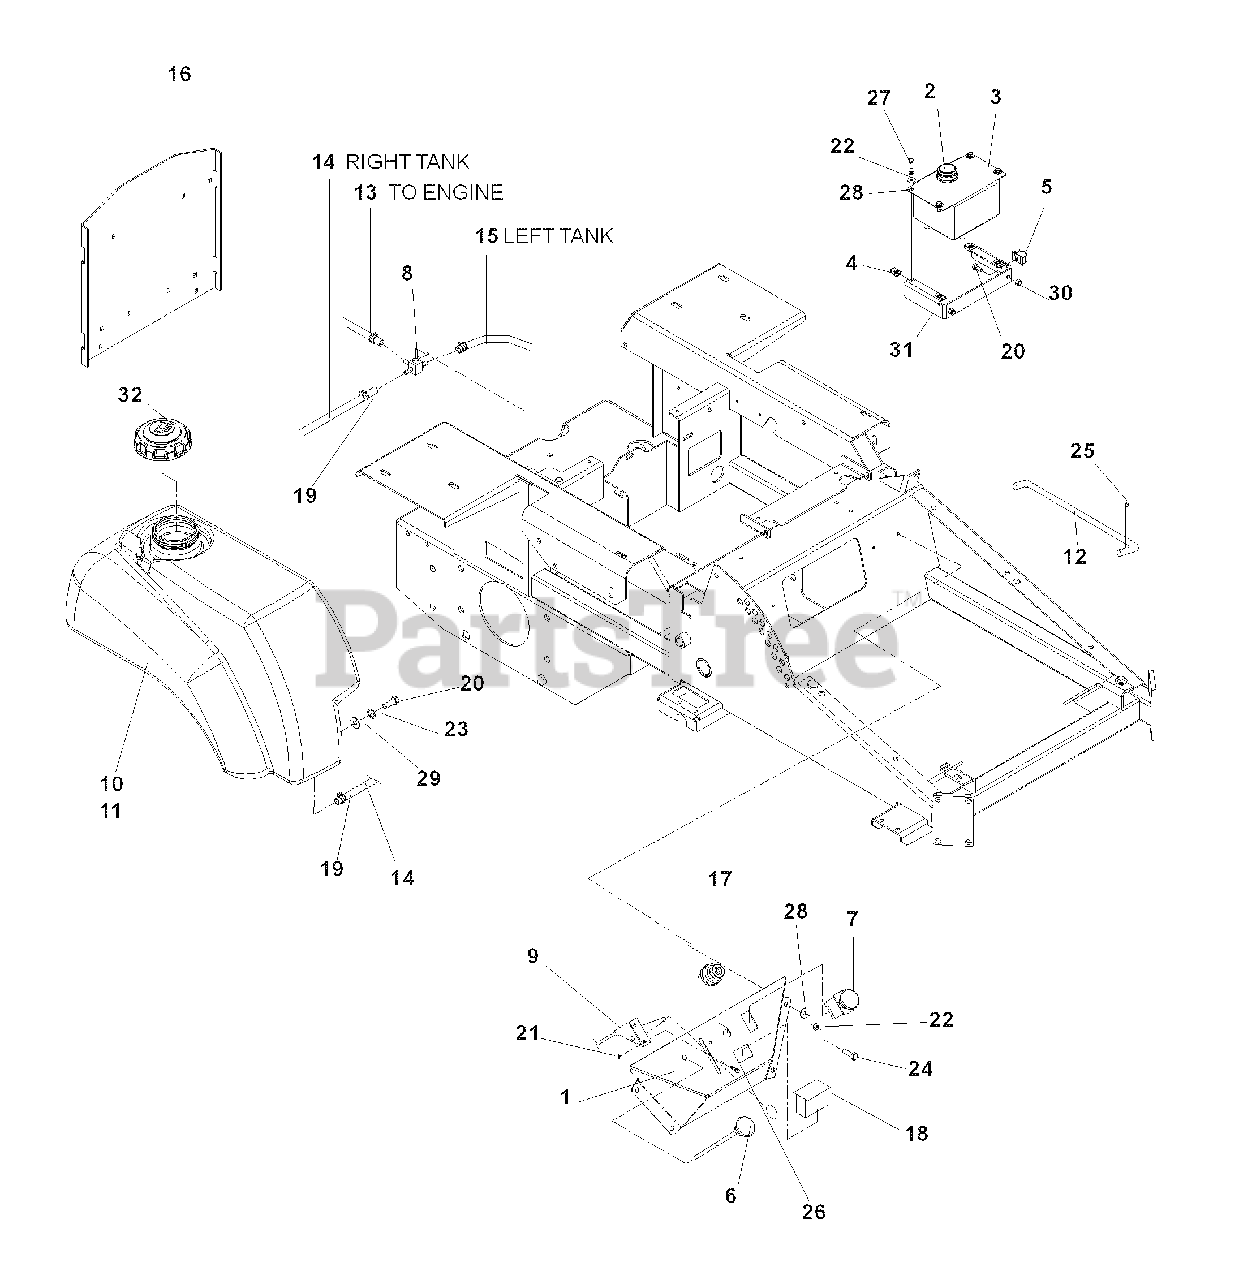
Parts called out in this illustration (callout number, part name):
1	CONSOLE W/DECALS
2	CAP-HYDRO RESERVOIR
4	RETAINER, "U" TYPE
5	PUSH-MOUNT WIRE CLIP
6	CHOKE CABLE MODELS: 968999258,968999307, 968999308, 968999332, 968999528
7	SWITCH
8	VALVE, FUEL
9	CONTROL, THROTTLE
10	TANK, FUEL, LEFT
11	TANK, FUEL, RIGHT
13	FUEL LINE
14	FUEL LINE
16	ENGINE GUARD
17	IGNITION SWITCH
18	HOUR METER
19	CLAMP, HOSE
20	HCS, 5/16-18 x 3/4
21	NUT, #10-24, NYLOC
22	LOCKWASHER, 1/4
23	LOCKWASHER, 5/16
24	SCREW, 1/4-20 x 5/8, SLF TAP
25	PIN COTTER, 1/8 x 3/4
26	SCREW, #10-24 x 1/2
27	HCS, 1/4-20 x 3/4
28	WASHER, 1/4
29	WASHER, 5/16
30	NUT, 5/16-18, NYLOC
31	TANK MOUNT
32	FUEL CAP, ANTI-SPLASH
